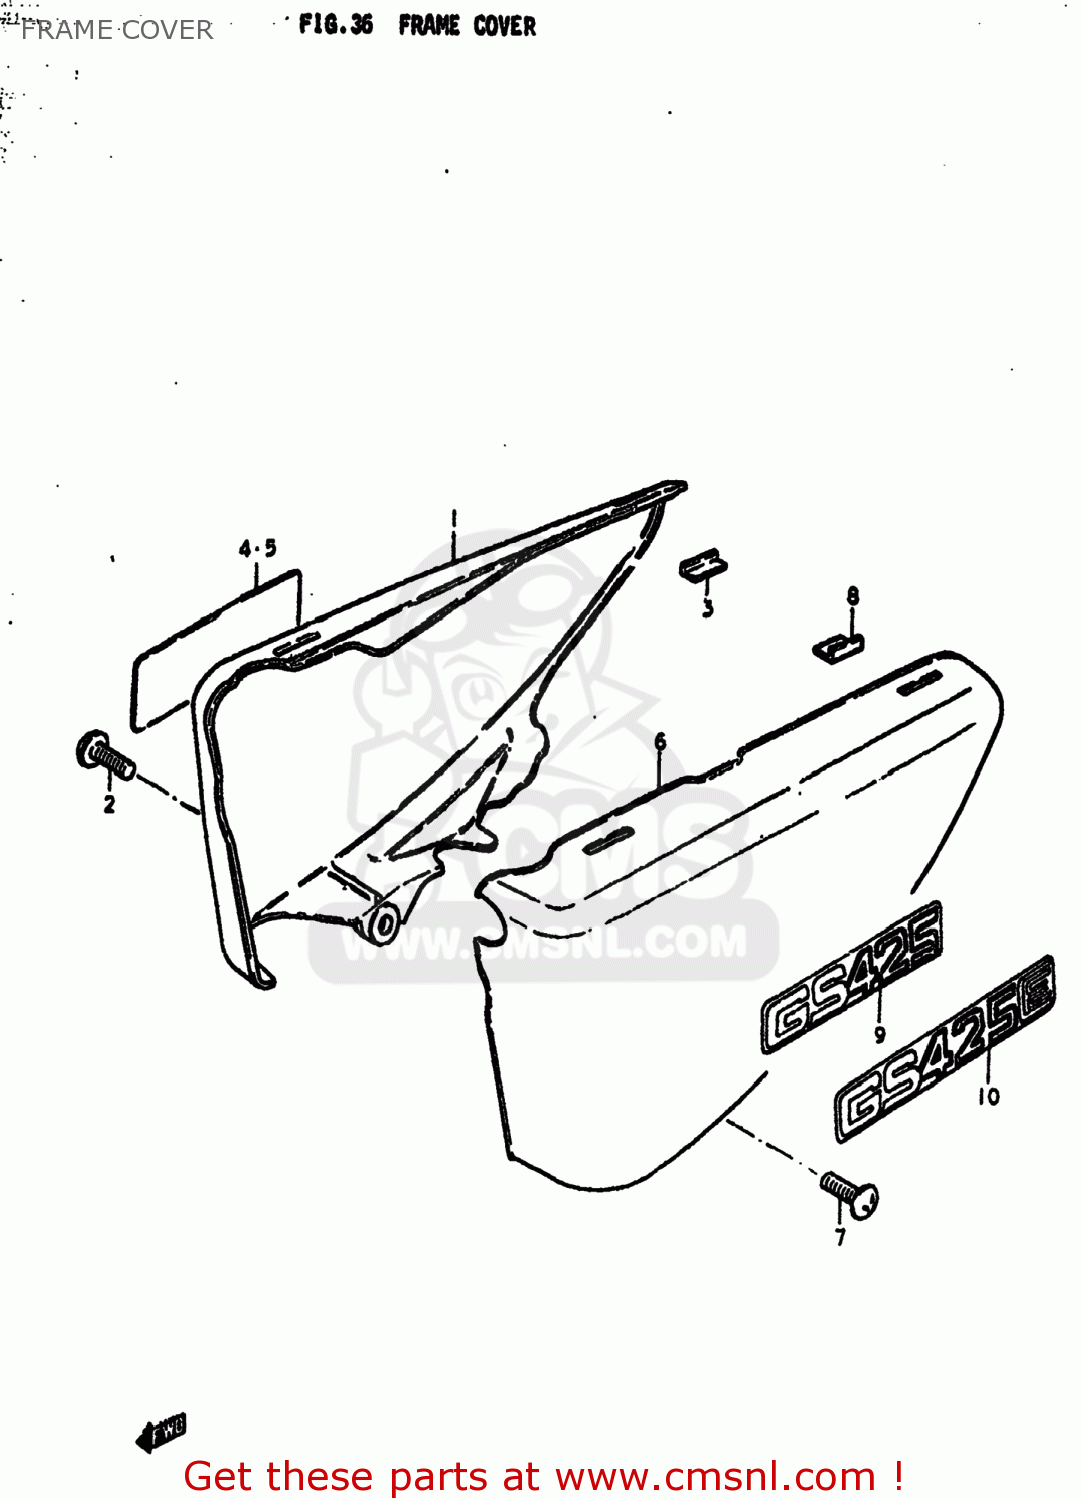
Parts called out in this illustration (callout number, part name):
1	COVER,FRAME,RIGHT
2	SCREW (6X15)
3	CUSHION,FRAME COVER
4	EMBLEM
5	EMBLEM,FRAME COVER
6	COVER,FRAME,LEFT
7	SCREW
8	CUSHION,FRAME COVER
9	EMBLEM
10	EMBLEM,FRAME COVER
